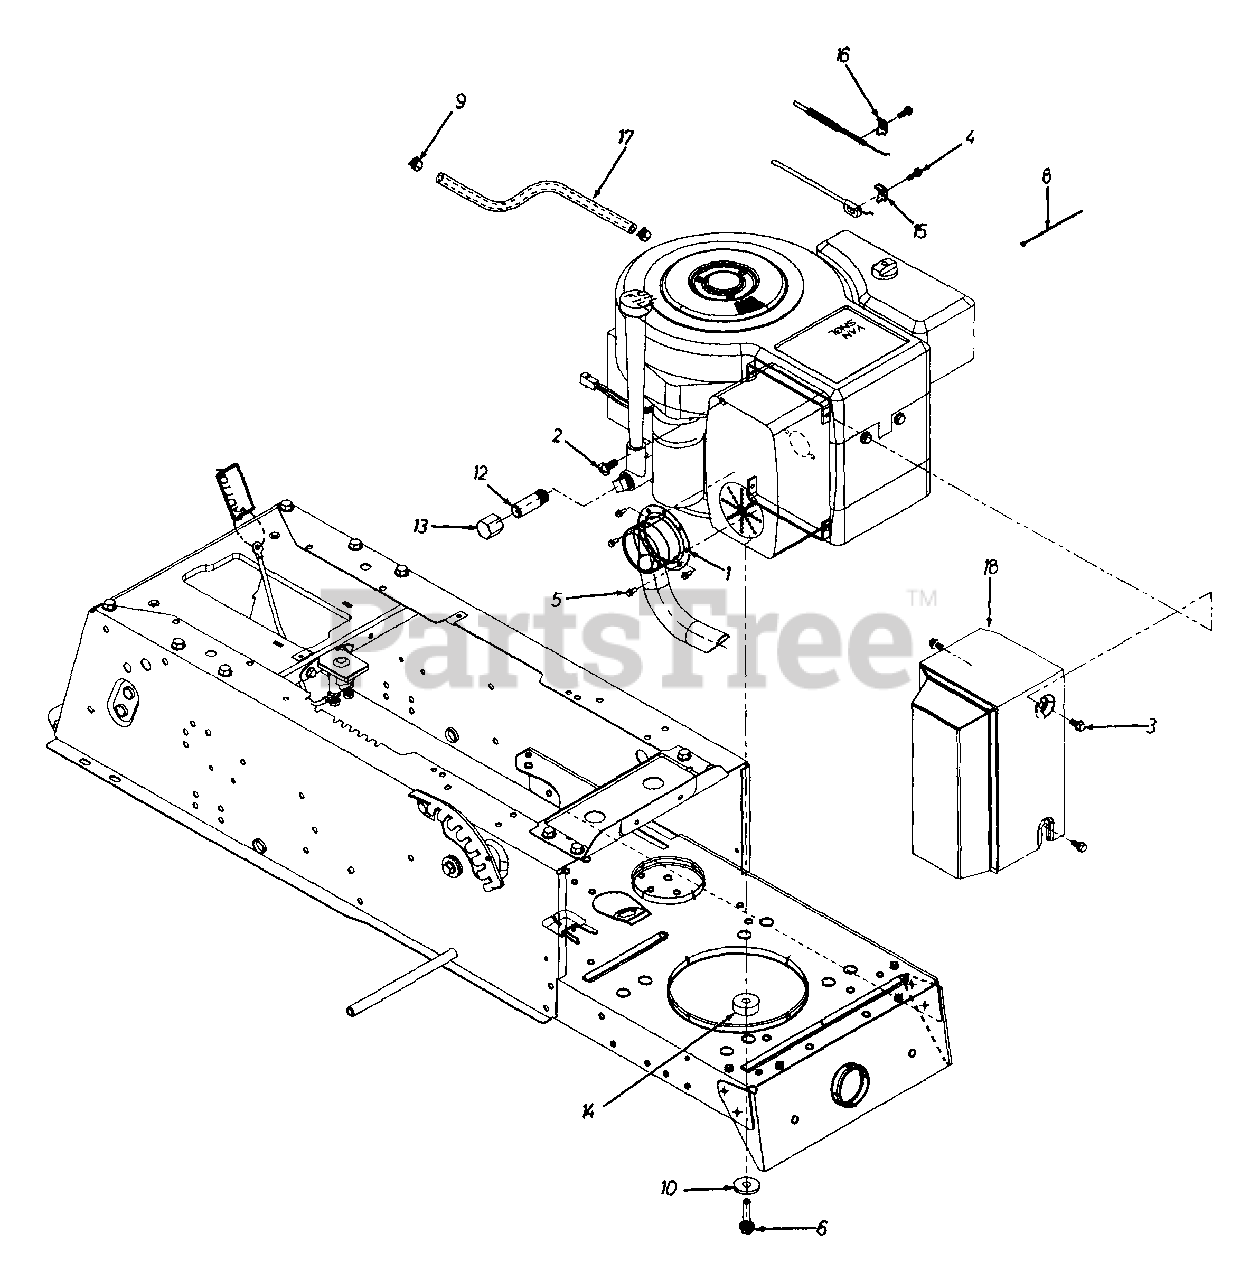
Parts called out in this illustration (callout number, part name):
1	Exhaust Pipe Ass'y.
2	Pan Hd. Mach. Scr. 5/16-18 x .75" Lg.
3	Hex Wash. Hd. Scr. 1/4 x 20 x .5" Lg.
4	Hex Wash. Hd. Scr. #10-32 x 5/8" Lg.
5	Hex Wash. Tap Scr. #8-32 x .38" Lg.
6	Hex L-Wash. TT-Tap Scr. 3/8-16 x 1.5" Lg.
10	Fl-Wash. 3/8" I.D. x 1.25" O.D.
12	Pipe Nipple 3/8-18 NPT.
13	Oil Drain Cap
14	Shld. Spacer .38" I.D. x 1.25"
15	Casing Clamp
17	Fuel Line
18	Muffler Heat Shield Ass'y.
